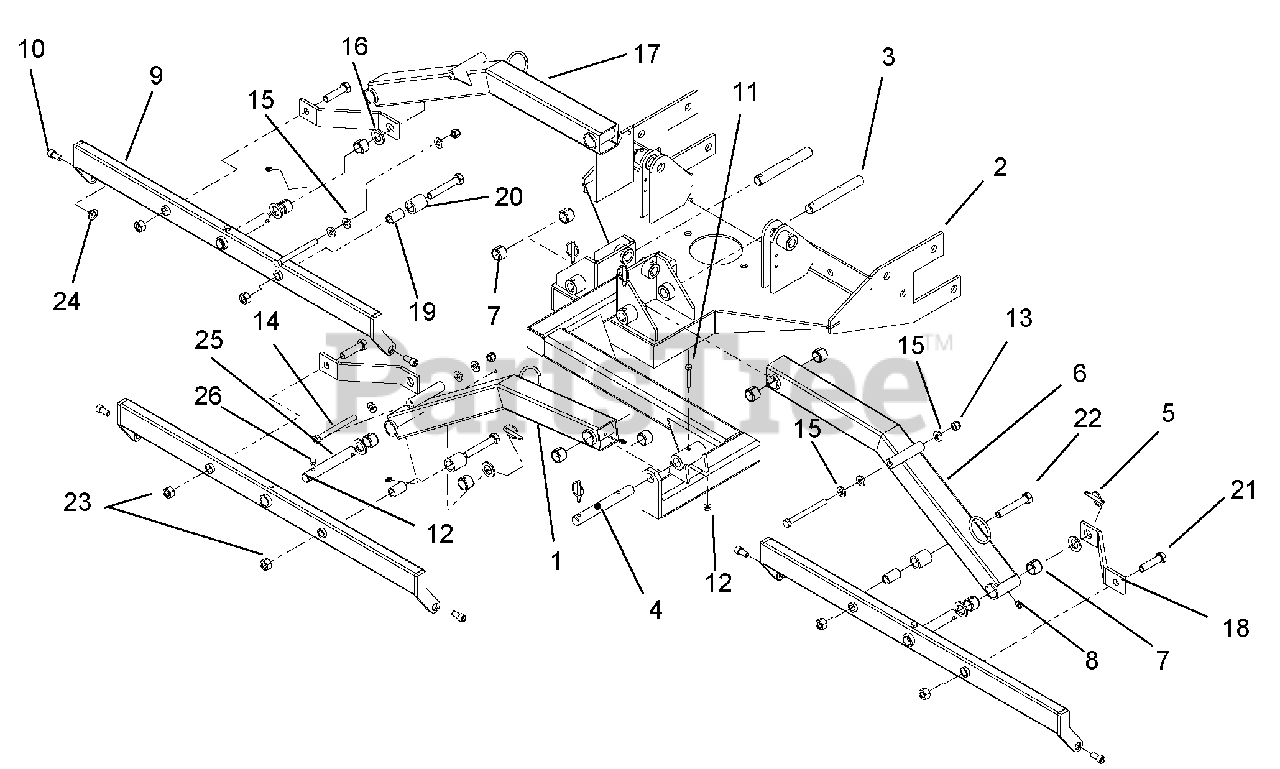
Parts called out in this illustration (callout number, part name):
1	ARM WELDMENT, CENTER
2	HYDROSTAT DECK WELDMENT
3	PIVOT PIN (CENTER)
4	PIVOT PIN (OUTER)
5	LYNCH PIN, 1/4 X 1-9/16
6	ARM WELDMENT, LEFT SIDE
7	BUSHING, 1 X 3/4 X 3/4
8	GREASE FITTING, 1/4-28
9	PIVOT ARM ASSEMBLY
10	HEX SOC HD CPSC 3/8-16 X 3/4
11	HHCS 1/4-20 X 1-3/4 G5
12	SERATED FLG NUT 1/4-20
13	HEX NUT, 3/8-16 NYLOCK
14	BOLT, HEX, 3/8-16 X 4-1/2
15	FLATWASHER, 3/8 HARDENED
16	WASHER, 3/4 SAE
17	ARM WELDMENT, RIGHT SIDE
18	SUPPORT BRACE
19	TRANSPORT BUMPER TUBE
20	BUMPER HOSE
21	HEX HD CPSC 1/2-13 X 2
22	HEX HD CPSC 1/2-13 X 3
23	SERATED FLG NUT 1/2-13
24	BUSHING, SINTERED STEEL
25	PIVOT PIN (REEL)
26	HEX HD CPSC 1/4-20 X 2-1/4
